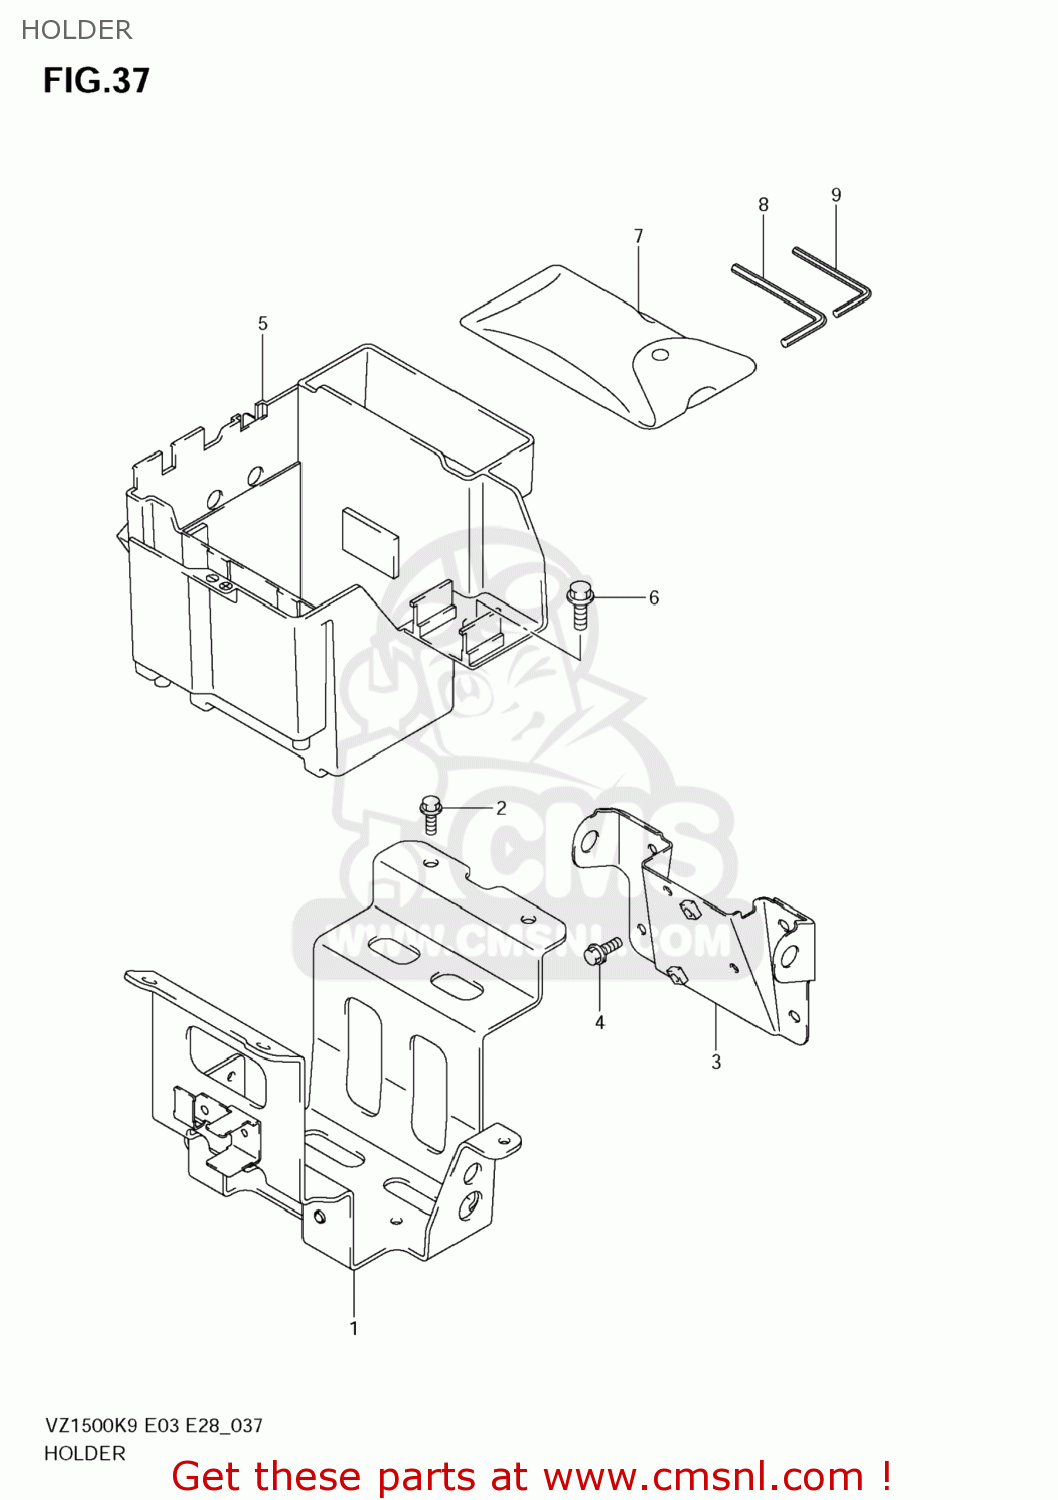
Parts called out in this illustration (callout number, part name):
1	HOLDER,BATTERY
2	BOLT
3	BUIS
4	BOLT
5	HOLDER,ELECTRIC PARTS
6	BOLT(6X16)
7	TOOL ASSY
8	SPANNER,HEXAGON(6)
9	HEXAGON SPANNER,5
